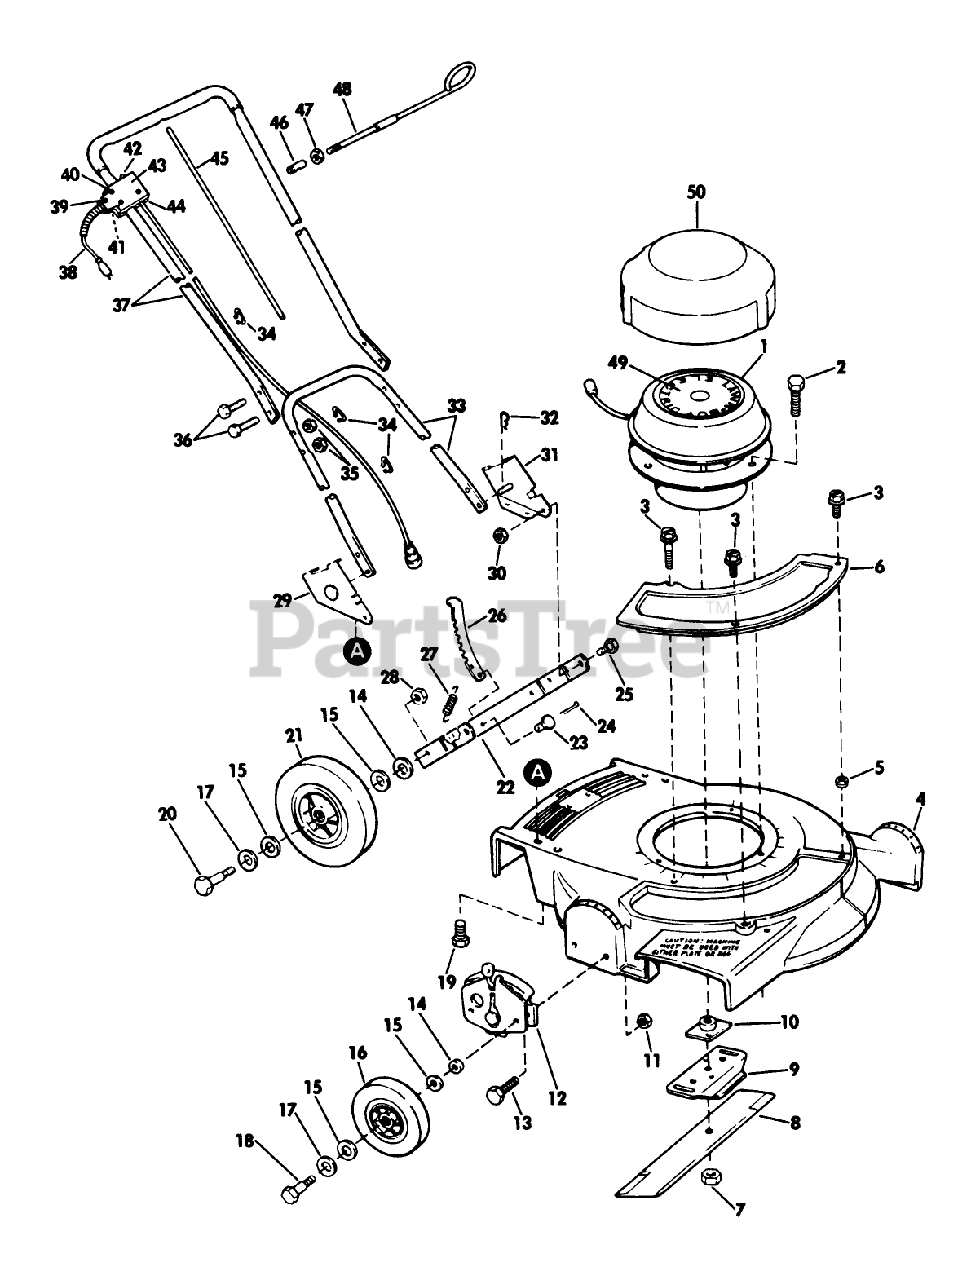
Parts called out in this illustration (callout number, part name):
2	SCREW
3	SCREW SEMS TRM HEX HD
7	NUT-BLADE
10	PLATE AND COLLAR ASM
11	NUT
14	WASHER WROUGHT
15	WASHER
17	SPACER
18	BOLT WHEEL
20	BOLT
25	BOLT-SHOULDER
27	SPRING N.A.S
28	LOCKNUT
30	NUT
32	HAIR PIN
36	SCREW
39	Screw-Ground
41	NUT S
